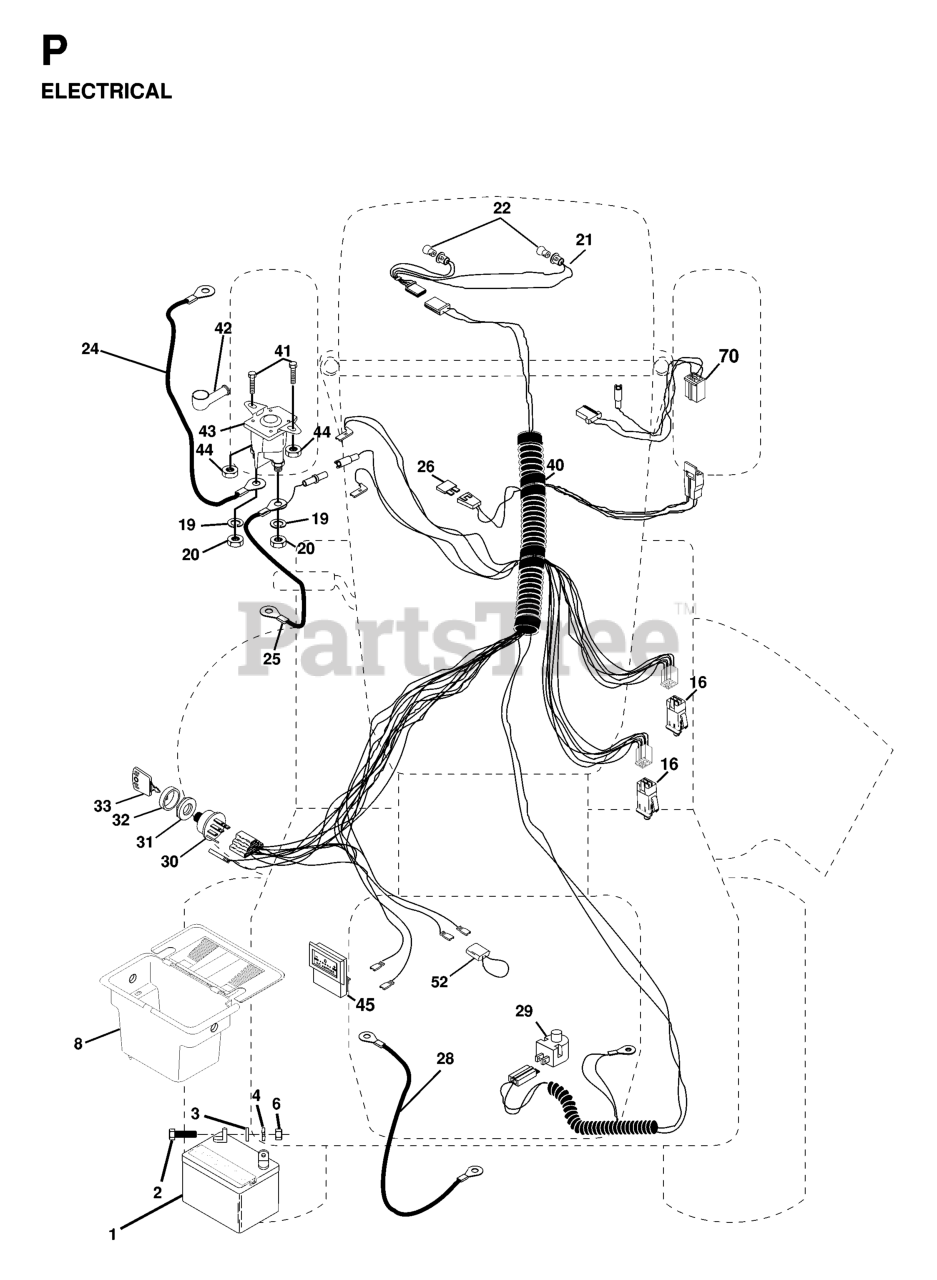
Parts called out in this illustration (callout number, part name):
1	BATTERY 12 VOLT 25 AMP
2	BOLT.HEX.1/4.X.3/4.DICHROMATE
4	LOCKWASHER
6	NUT
8	CASE BATTERY MECH HINGE
16	SWITCH INTERLOCK
19	LOCKWASHER
20	NUT
21	HARNESS LIGHT SOCKET
24	BATTERY CABLE GT
25	CABLE BATTERY
28	CABLE T
29	RP.SWITCH.PLUNGER.NC.GRAY
30	SWITCH.IGNITION.4.POSITION
31	NUT IGNITION
32	COVER SWITCH KEY
33	KEY.MOLDED.GENERIC
40	HARNESS IGN
41	BOLT
42	TERMINAL COVER
43	SOLINOID
44	Nut, Keps Blk Hex 1/4-20 UNC
45	AMMETER
52	WIRE PROTECTION LOOP
70	HARNESS, ENGINE
